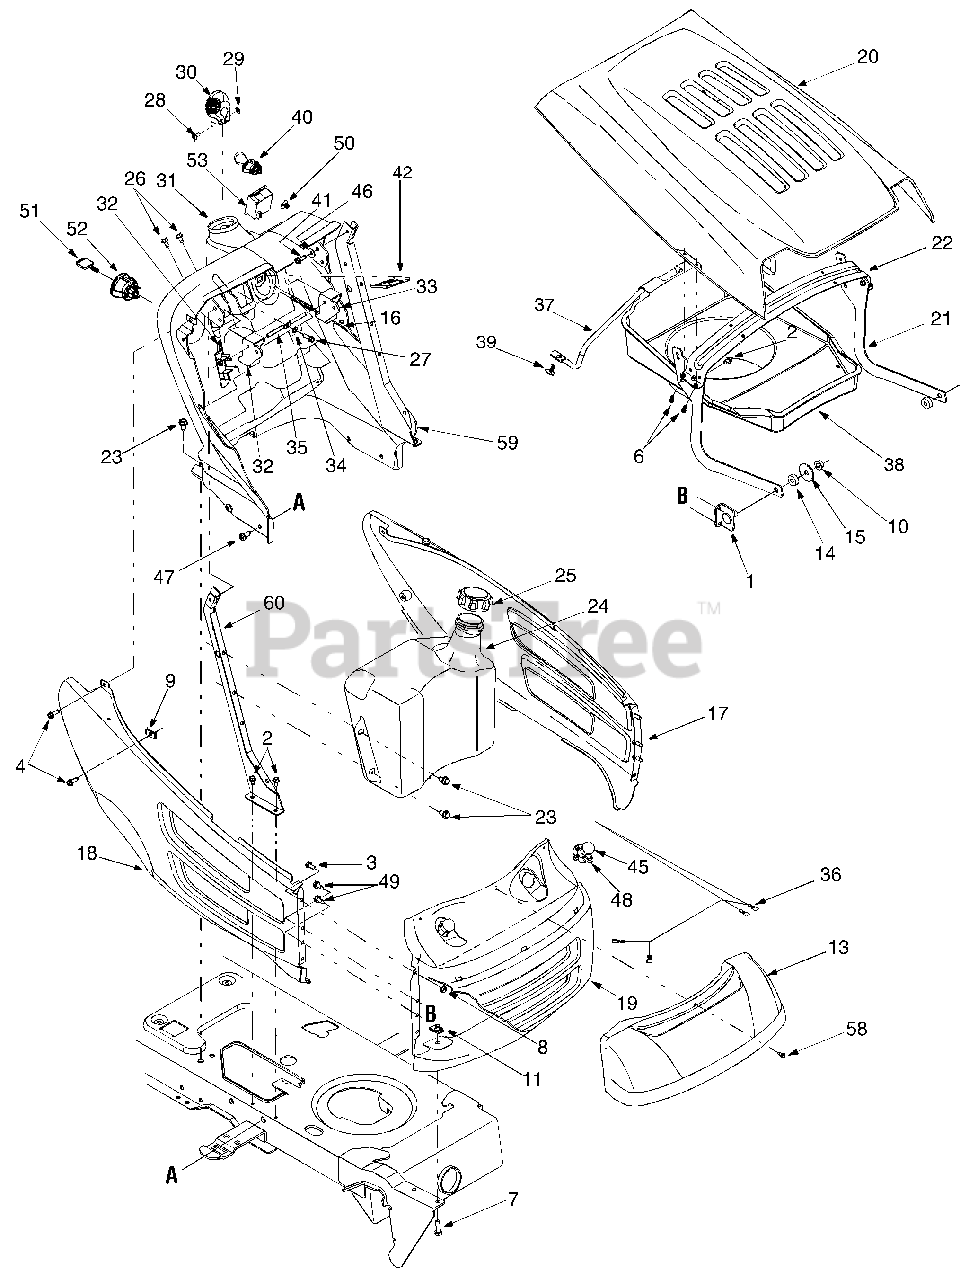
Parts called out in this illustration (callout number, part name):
2	Self-tapping Screw, 1/4-20 x .5
3	Hex Cap Screw, 1/4-20 x .62
4	Phillips Pan Screw, 1/4-20 x .75
6	Screw, #10-16 x .5
7	Hex Cap Screw, 5/16-18 x 1.0
8	Hex Sems Nut, 1/4-20
9	U-type Speed Nut, 1/4-20
10	Flange Lock Nut, 3/8-16
11	U-nut, 5/16-18
13	Headlight Lens
14	Rubber Washer, .87 x .33
15	Flat Washer, .406 x 1.5 x 11GA
16	Choke Knob/Cable (B&S OHV V-Twin)
24	Fuel Tank, Three Gallon
25	Fuel Cap (fits either tank)
26	Screw, 1/4-14 x .625
27	Self-tapping Screw, 1/4-15 x .75
28	Truss Phillips Screw, #8-32 x .375
29	Hex Nut, #8-32
30	Throttle Control Knob
31	Dash Panel (Models w/ Electric PTO)
32	Cruise Control Button
33	Parking Brake Button
34	Flat Washer, 9/32 x 1/2 x 1/16
35	Brake/Cruise Pivot Rod
36	Headlight Wire Harness
37	Hood Plenum Support Rod
38	Hood Plenum, 2.85"
39	Ratchet Clip
40	Electric PTO Switch
41	Self-tapping Screw, 1/4-20 x .75
42	Switch Bracket, Electric PTO
45	Lamp
46	Bell Washer, .265 x .75 x .062
47	Screw, 5/16-18 x .75
48	Headlight Socket
49	Hex Index Screw, 1/4-20 x .625
50	Choke Plug
51	Ignition Key w/ plastic cover
52	Ignition Switch
53	Systems Ind. Monitor w/ Hour Meter
58	Hex Screw, #10 x .50
